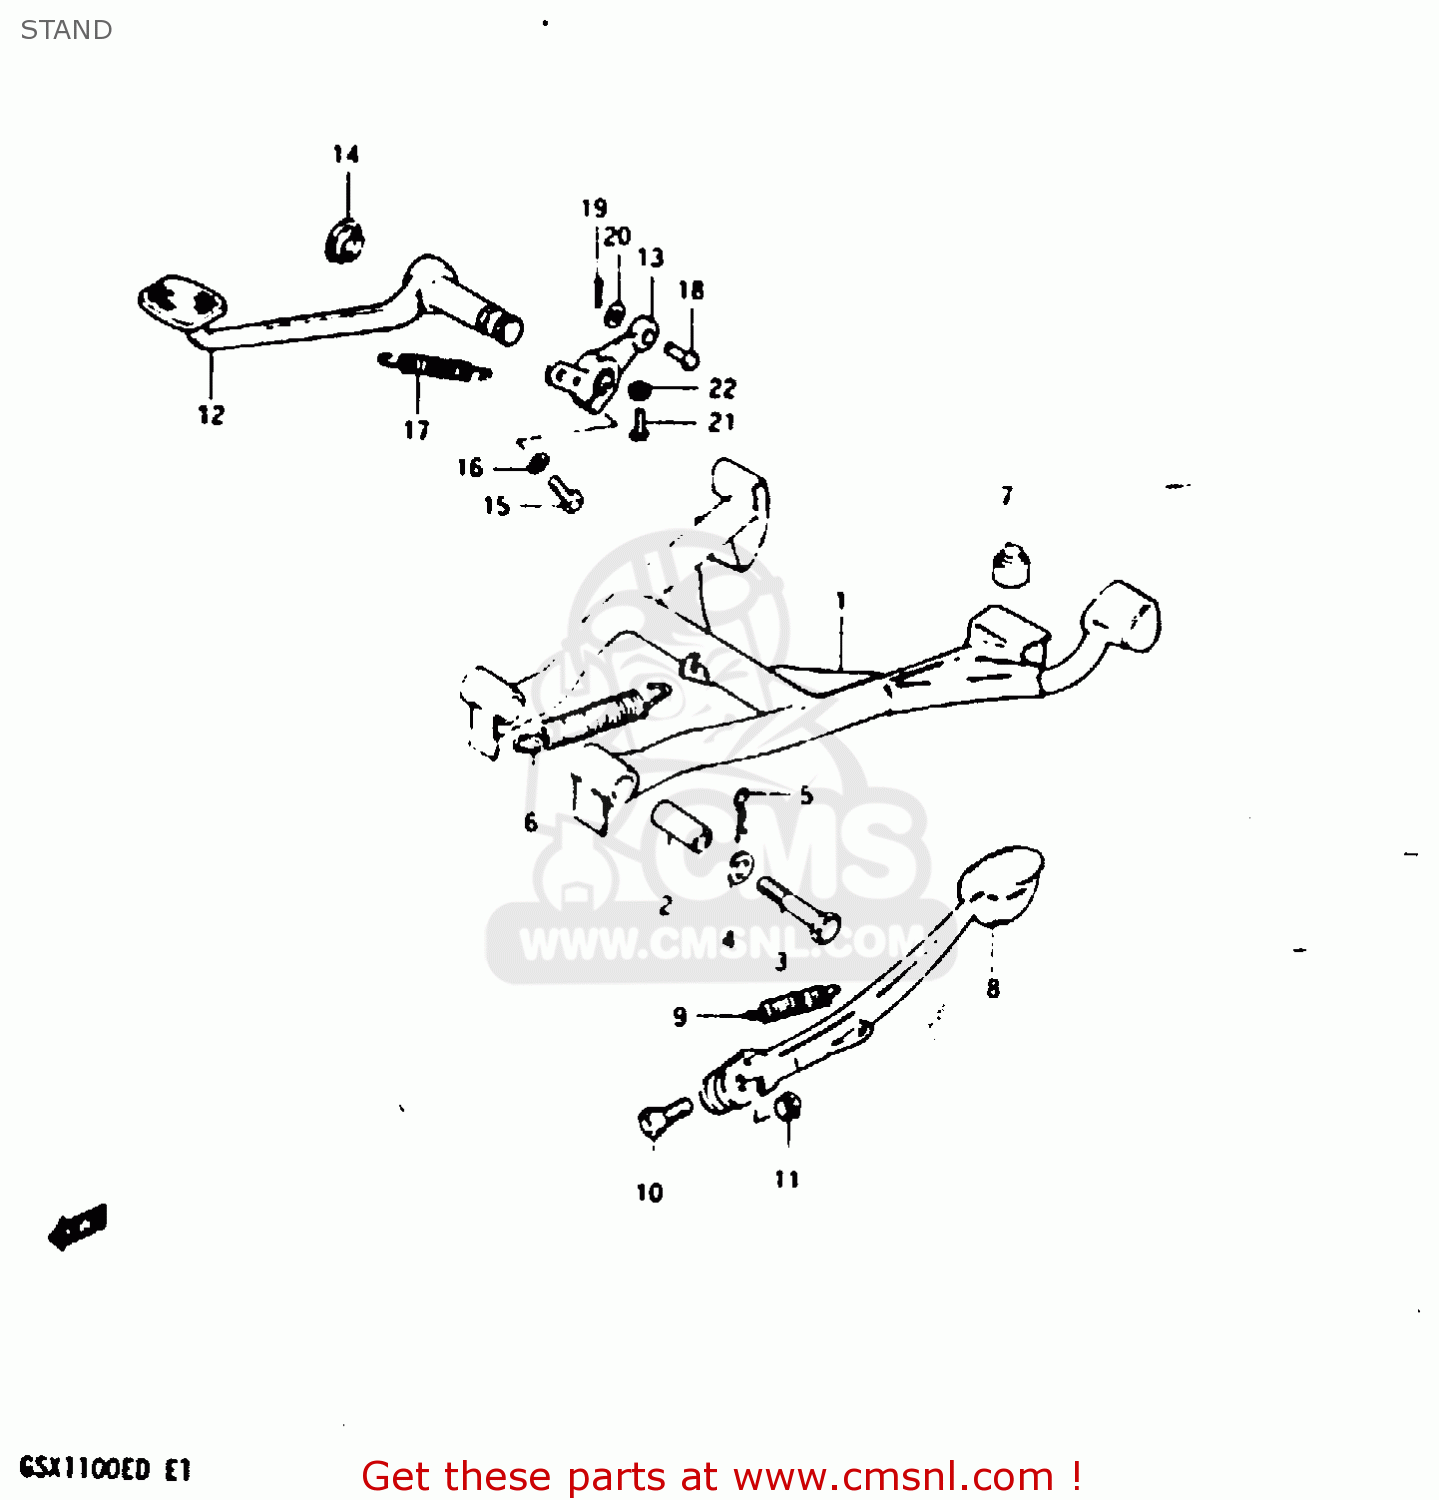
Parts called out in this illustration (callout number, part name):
1	STAND,CENTER
2	SPACER(10X16X38.8)
3	BOLT
4	LOCK WASHER
5	CLIP
6	SPRING
7	CUSHION
8	STAND,SIDE
9	SPRING
10	BOLT(10X30)
11	NUT
12	PEDAL,BRAKE
13	ARM,BRAKE PEDAL
14	CAP, BRAKE PEDAL
15	BOLT
16	LOCK WASHER
17	SPRING
18	PIN
19	PIN
20	WASHER
21	BOLT
22	NUT
